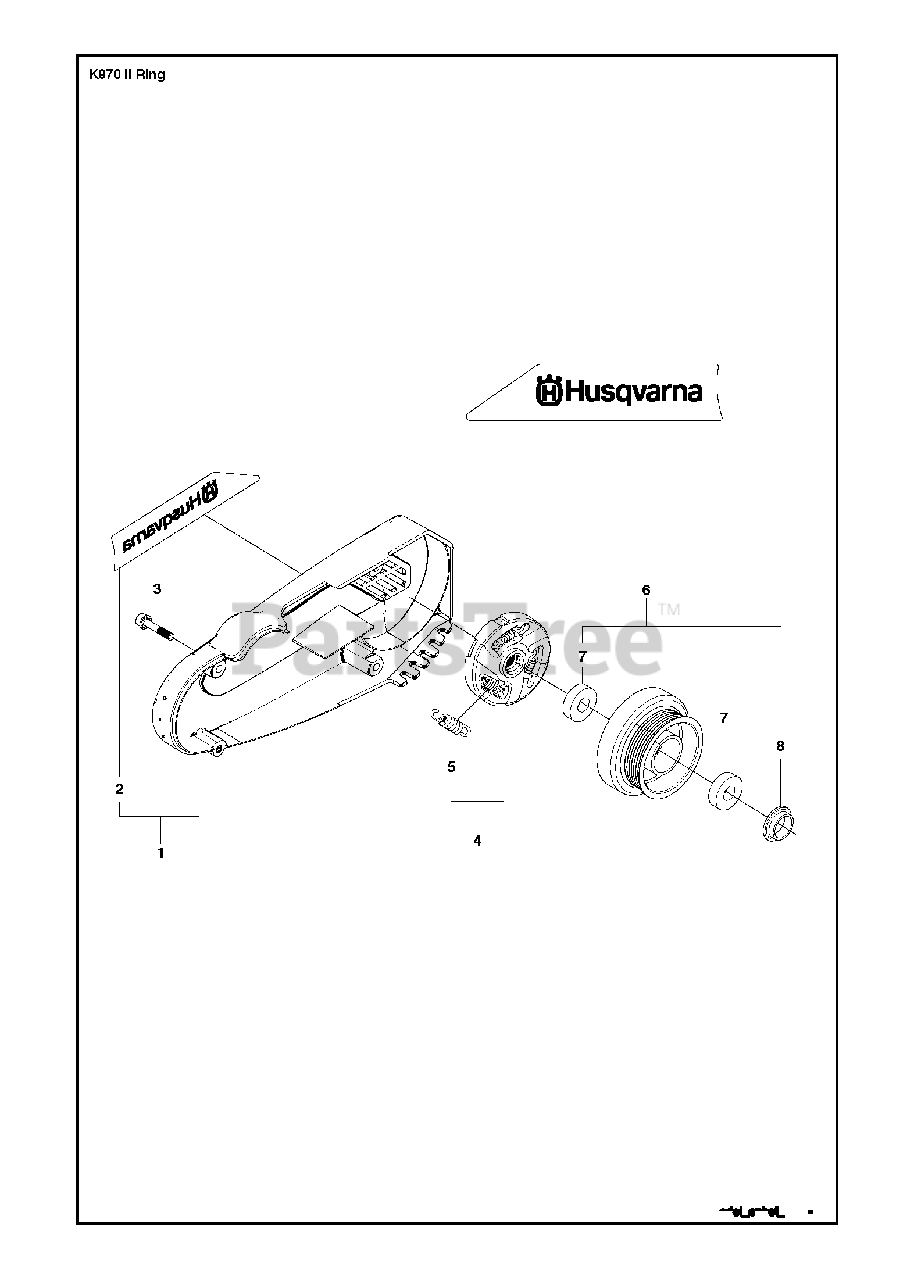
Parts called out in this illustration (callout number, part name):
3	SCREW ITXSCM
4	CLUTCH ASSYIncl. 5
5	CLUTCH SPRING
6	DRIVING PULLEY ASSYIncl 7 - 8
7	BALL BEARING
